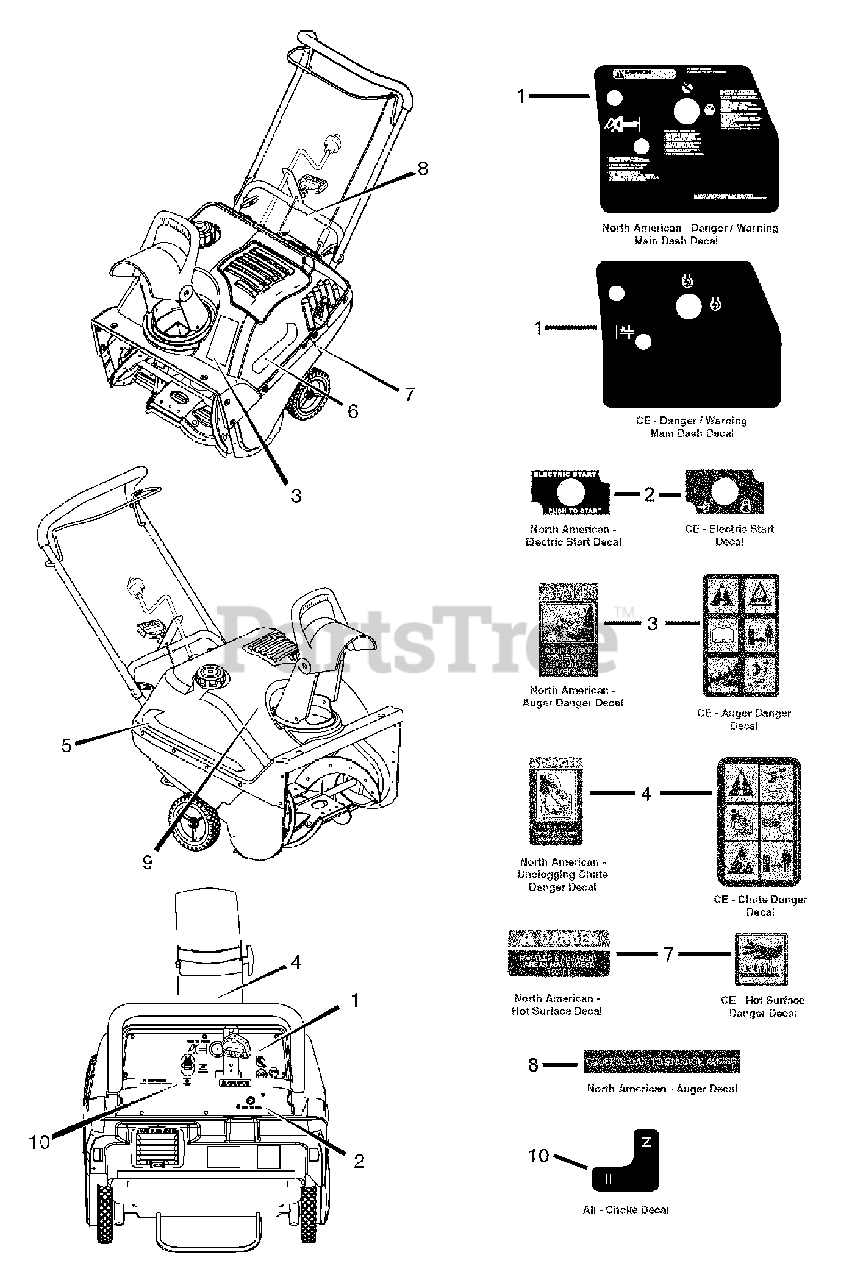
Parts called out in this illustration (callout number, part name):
1	DECAL, Control Panel - North American 22"
1	DECAL, Control Panel CE 22"
2	DECAL, Electric Start - North American
2	DECAL, Electric Start - CE
3	DECAL, Danger Auger - North American
3	DECAL, Danger Auger - CE
4	DECAL, Danger Chute - North American
4	DECAL, Danger Chute - CE
5	DECAL, Simplicity R.H.
6	DECAL, Simplicity L.H.
7	DECAL, Hot Muffler - North American
7	DECAL, Hot Muffler - CE
8	DECAL, Auger Control
9	DECAL, Briggs & Stratton
10	DECAL, 5022 R.H.
